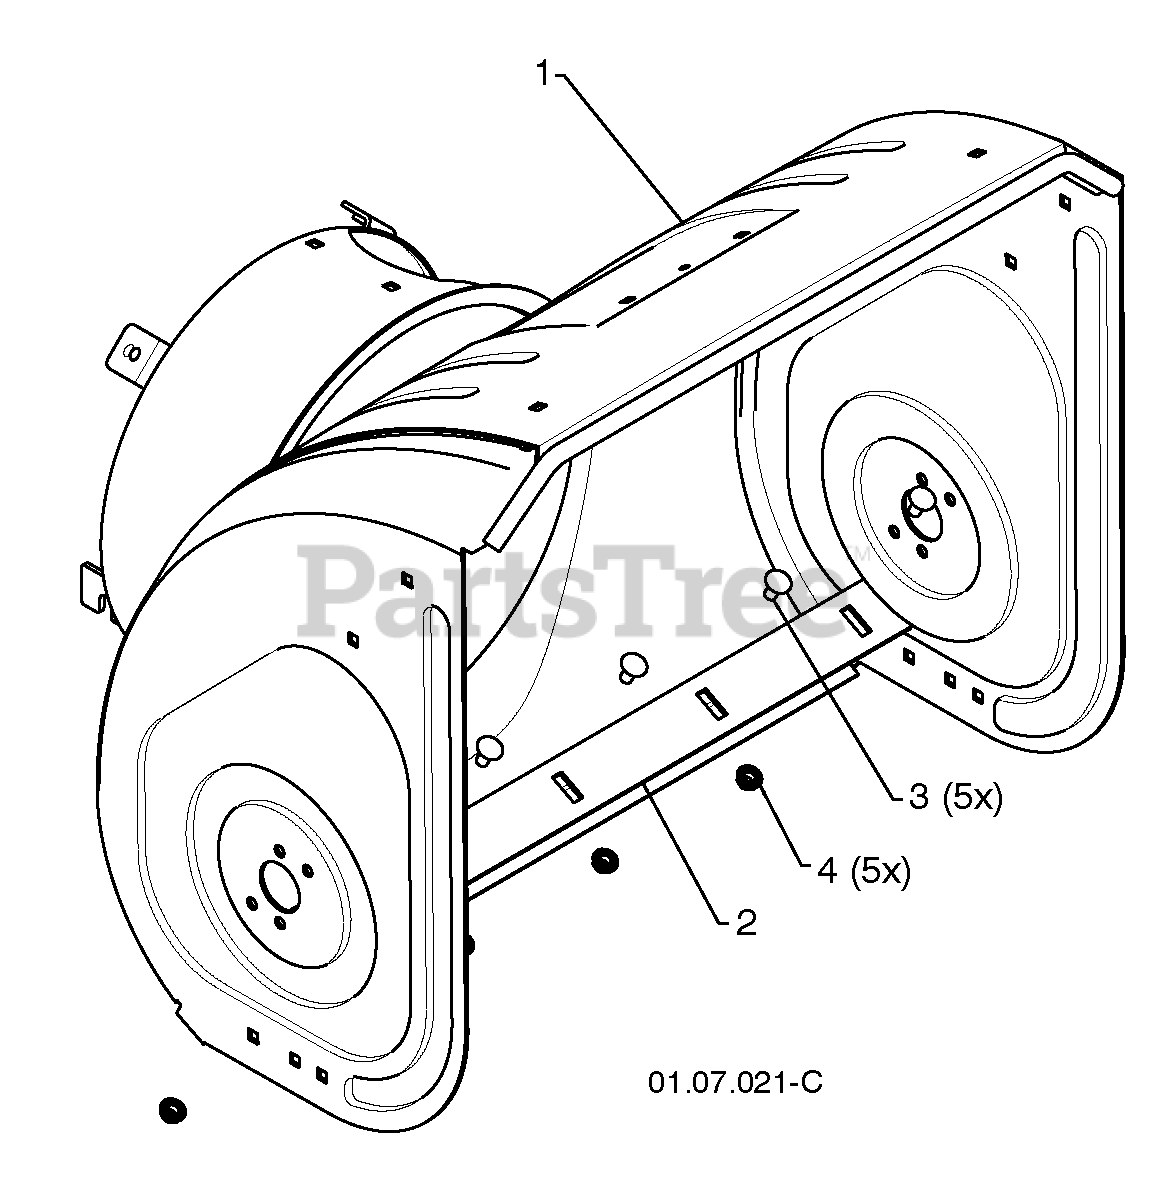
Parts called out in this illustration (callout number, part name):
1	AUGER HOUSING
2	SCRAPER BAR
3	CARRIAGE BOLT 5/16-18 X .625
4	NUT 5/16-18
